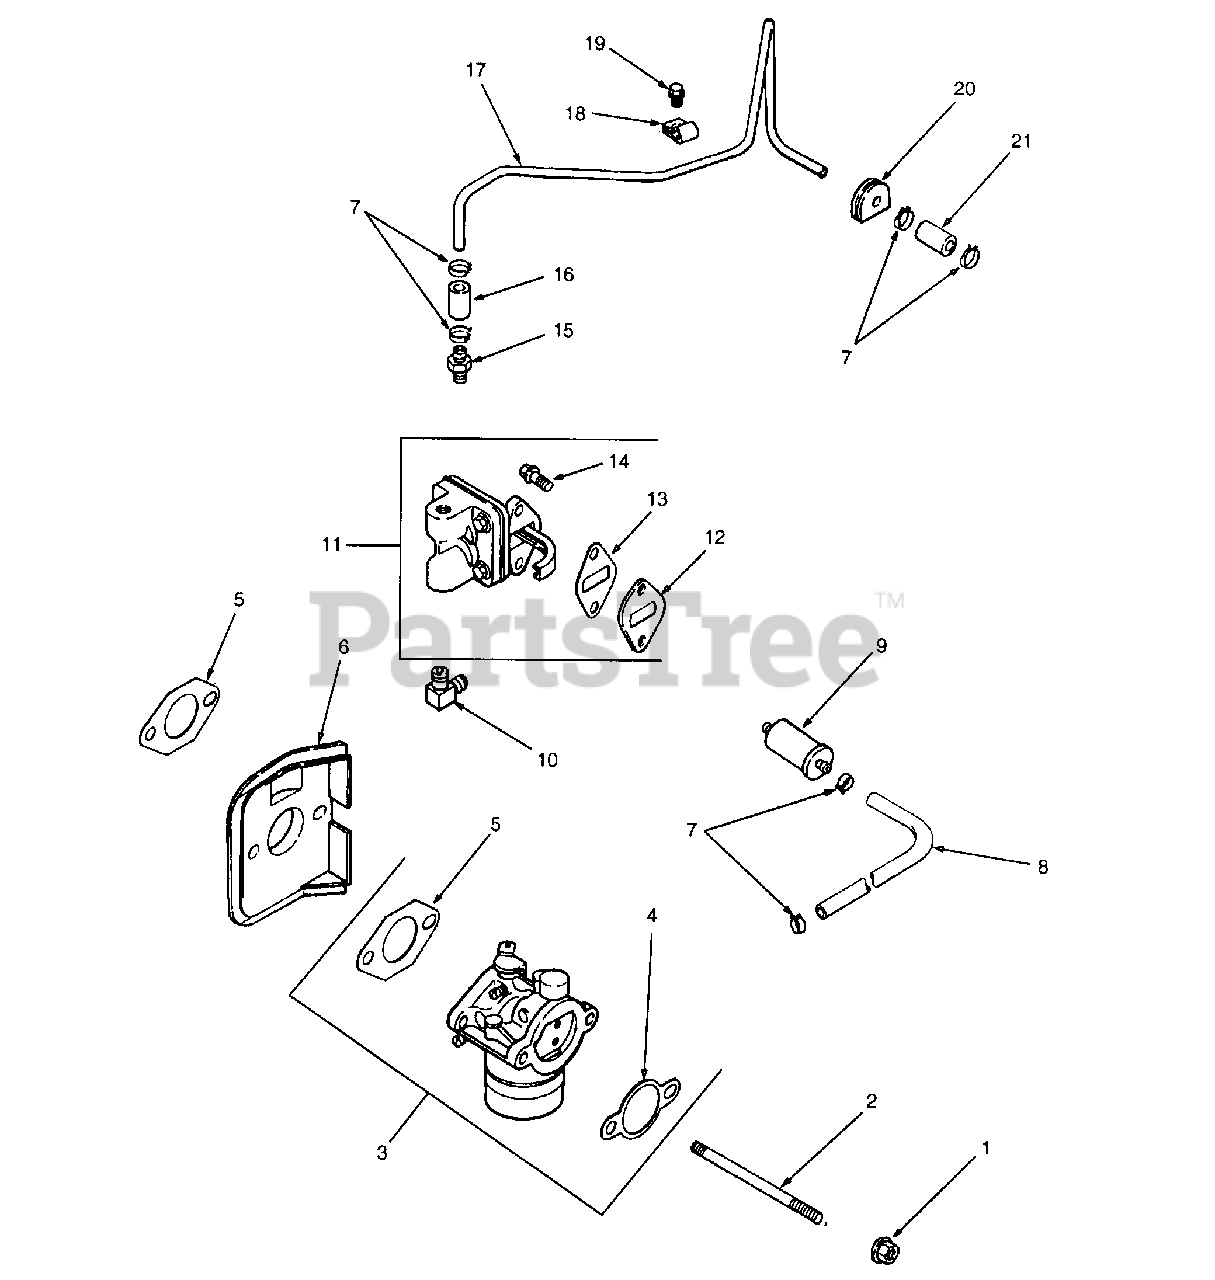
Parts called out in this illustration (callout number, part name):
1	Nut, Hex Flange, M6 x 1.0
2	Stud, M6 x 1.0 x 122
3	Kit, Carburetor w/Gaskets
4	Gasket, Air Cleaner
5	Gasket, Carburetor
6	Deflector, Heat
7	Clamp, Fuel Line
8	Line, Fuel 3"
9	Filter, Fuel
10	Connector, 90° Hose
11	Kit, Fuel Pump
12	Spacer, Fuel Pump
13	Gasket, Fuel Pump
14	Screw, Hex Flange, M6 x 1.0 x 20
15	Connector, Straight Hose
16	Line, Fuel 2-1/2"
18	Clamp, Fuel Line
19	Screw, Hex Flange, M5 x 0.8 x 10
21	Line, Fuel 1-1/4"
